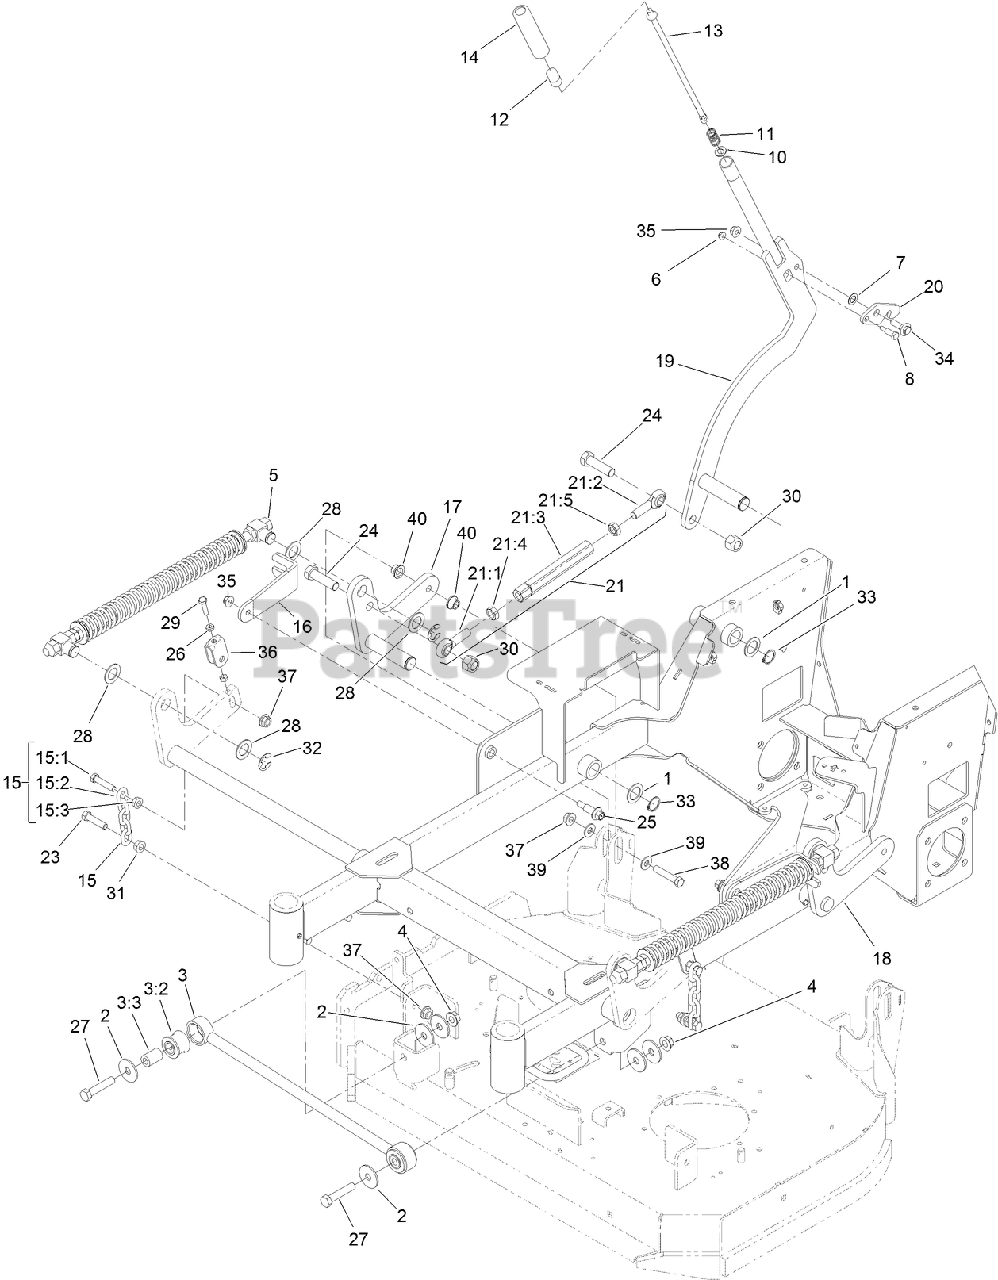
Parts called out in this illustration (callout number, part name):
1	WASHER-SPACER
2	WASHER-THRUST
3	PANHARD ROD ASM
3:2	BUSHING-SUSPENSION, RUBBER
3:3	SPACER
4	NUT-HF
5	DECK LIFT SPRING ASM
6	NUT-HF
7	WASHER
8	BOLT-SHOULDER
10	WASHER-SPECIAL
11	SPRING-COMPRESSION
13	ROD-LATCH, RELEASE
15	DECK LIFT CHAIN ASM
15:1	CHAIN-LIFT, DECK
15:2	SCREW-HH
15:3	NUT-HF
16	BRACKET-FORK
17	ARM-LIFT, RH
18	ARM-LIFT, LH
19	ARM-LIFT, HOC
20	LATCH-HOC
21	DECK LIFT LINK ASM
21:1	BALLJOINT-SPHERICAL
21:2	BALLJOINT-SPHERICAL
21:3	LINK-LIFT, DECK
21:4	NUT-JAM
21:5	NUT-JAM
23	SCREW-HH
24	SCREW-HH
25	BOLT-SHOULDER
26	NUT-JAM
27	SCREW-HH
28	WASHER-FLAT
29	SCREW-HH
30	NUT-LOCK, NI
31	NUT-HF
32	RING-RETAINING, EXT
33	RING-RETAINING
34	SCREW-SHOULDER, HWH
35	NUT-HF, NI
36	YOKE-ADJUST, DECK
37	NUT-HF
38	SCREW-HH
39	WASHER-FLAT
40	BUSHING-FLANGED
